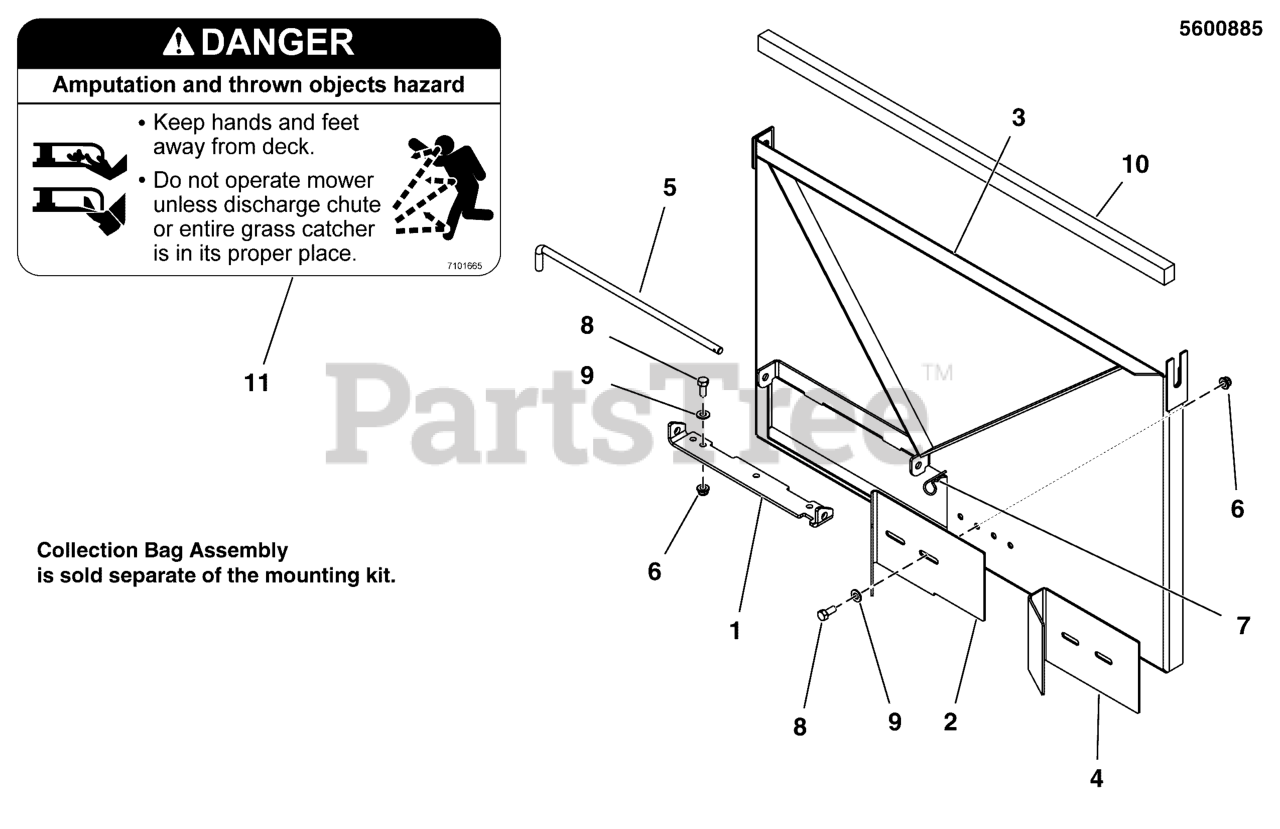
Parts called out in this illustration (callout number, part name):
1	PLATE, BAGGER MOUNT BRACKET - BLACK
2	PLATE, BLOCK OFF PLATE, 48/52" - BLACK
3	WELD, BAGGER MOUNT, 48/52" - BLACK
4	PLATE, BLOCK OFF, 52 - BLK
5	ROD, BAGGER MOUNT, 48/52"
6	NUT, 5/16-18 HEX NYLOCK FLANGE
7	PIN, HAIR, .0915 X 1-7/8
8	BOLT, 5/16-18 X 3/4 GD5
9	WASHER, 5/16" SAE
10	FOAM, 3/4 X 1 X 30.50
11	DECAL, DANGER DO NOT OPERATE W/O DEFLECT
